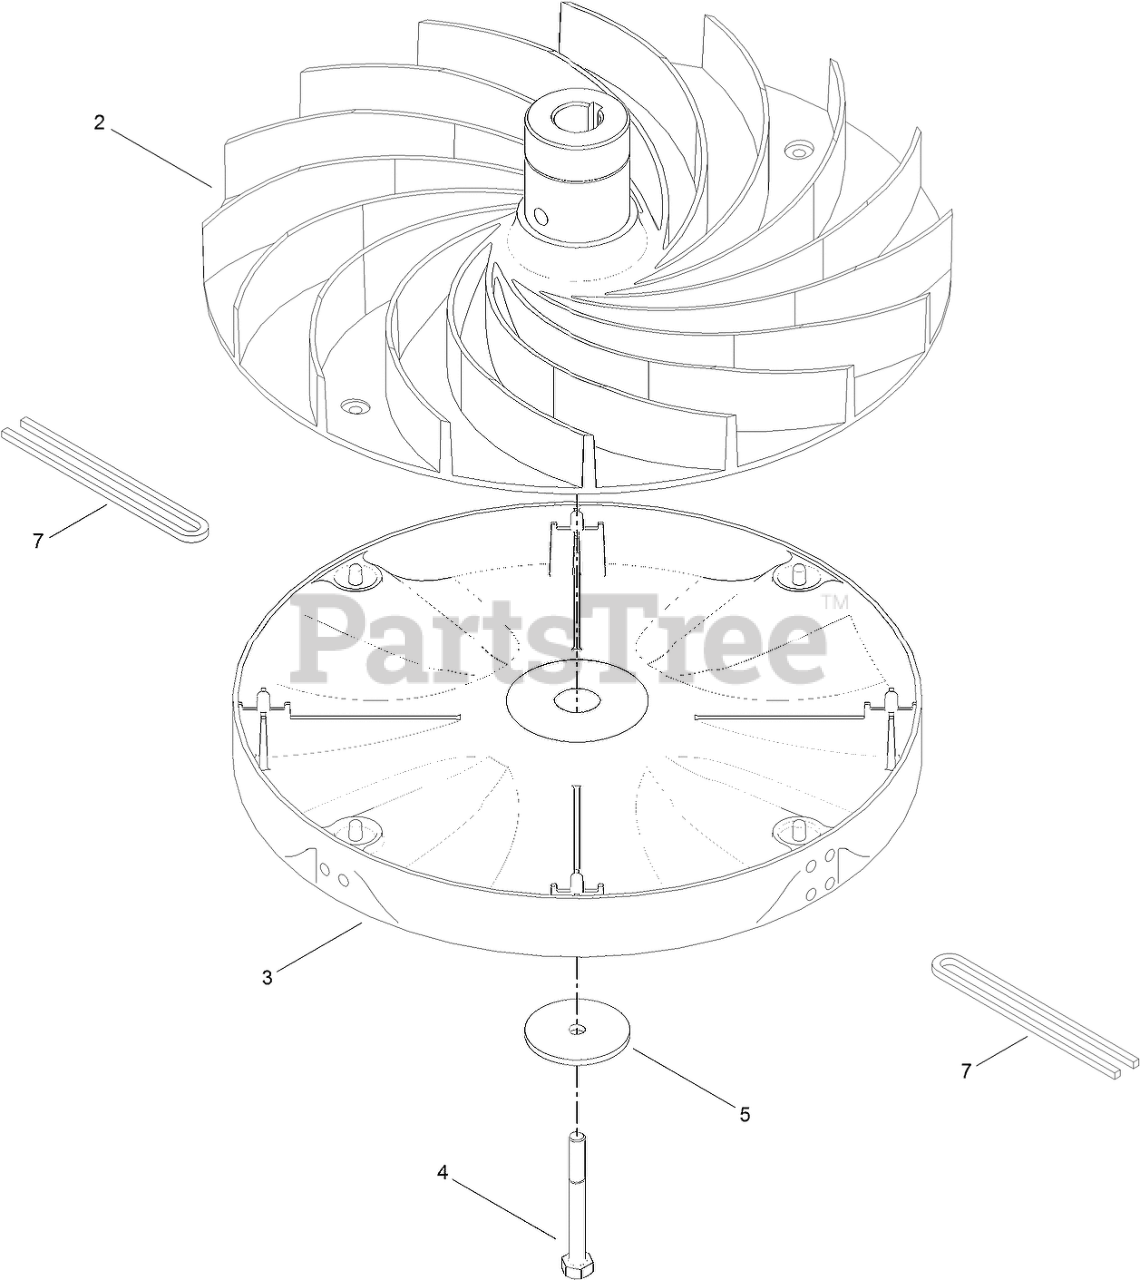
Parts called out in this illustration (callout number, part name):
2	IMPELLER
3	DISC-CUTTING
4	BOLT-HH
5	DISC-SPRING
7	LINE-CUTTING, NYLON
